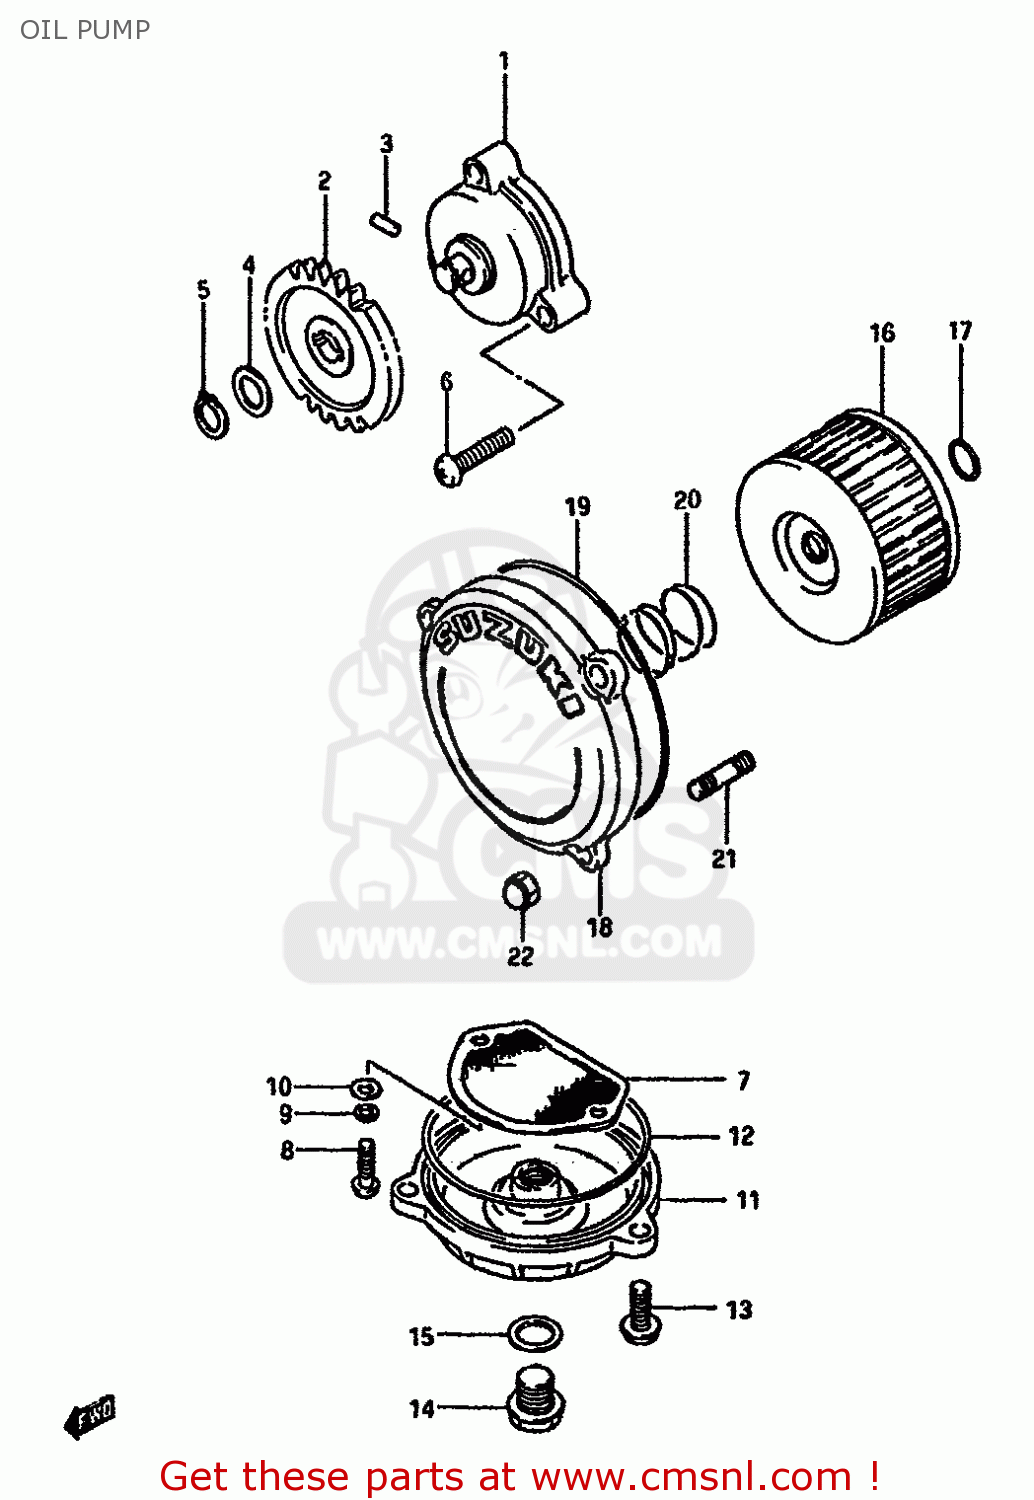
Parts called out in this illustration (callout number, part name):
1	PUMP ASSY,ENGINE OIL
2	GEAR,OIL PUMP DRIVEN
3	PIN(4X15.8)
4	SHIM
5	CIRCLIP
6	SCREW
7	STRAINER,ENGINE OIL
8	SCREW 5X12
9	LOCK WASHER
10	WASHER
11	CAP,OIL STRAINER
12	O RING(D:2.4,ID:85)
13	BOLT,REAR
14	PLUG
15	GASKET(14X19.2X2) (NAS)
16	FILTER,ENGINE OIL
17	O RING(D:2.4,ID:15.8)
18	CAP,OIL FILTER
19	O RING(D:2.4,ID:73)
20	SPRING
21	STUD 6X12
22	NUT 6MM
